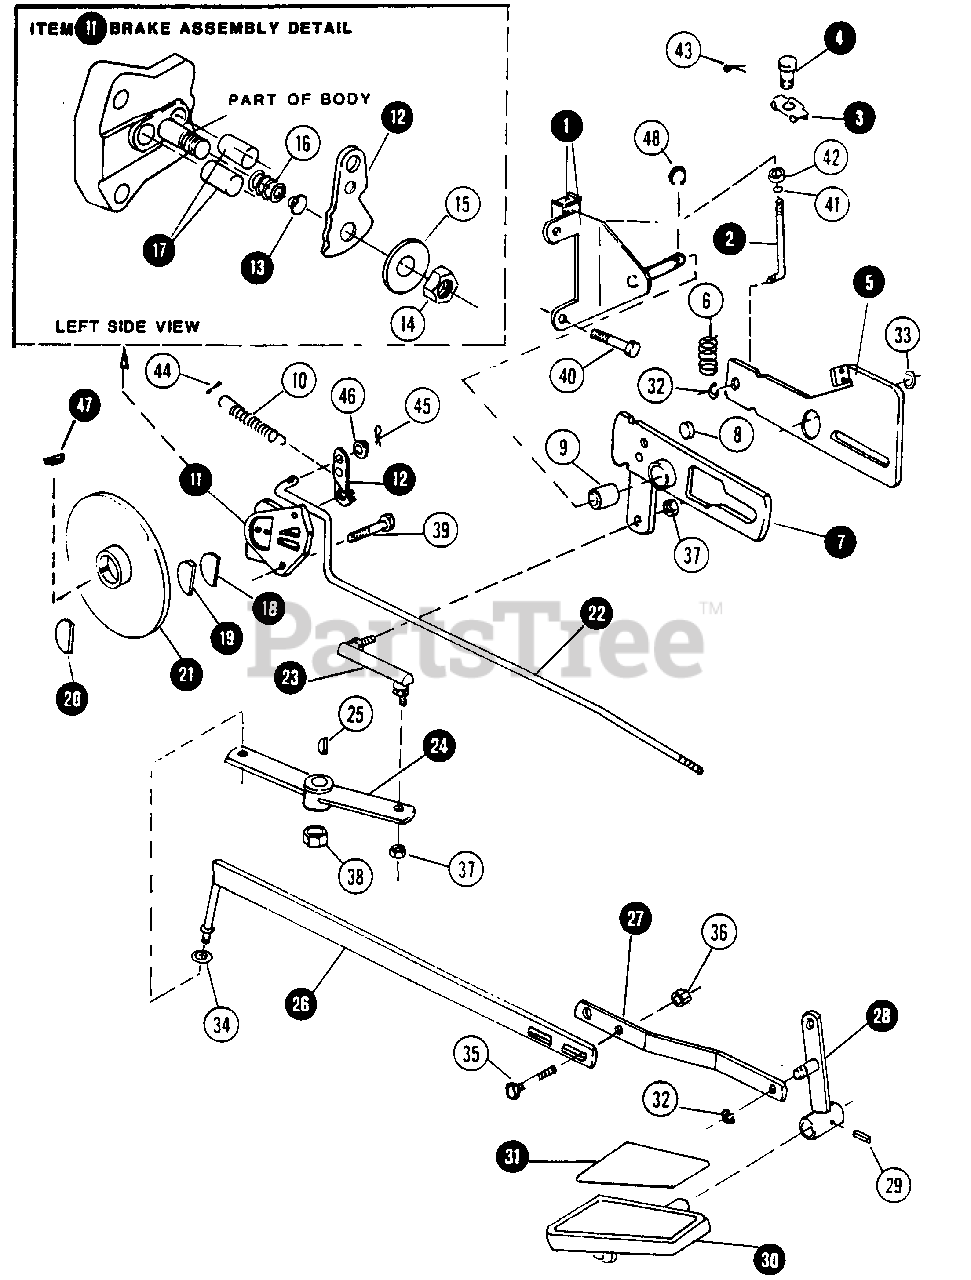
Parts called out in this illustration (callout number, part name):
1	BRACKET, TRUNNION MOUNTING
2	LINK, NEUTRAL ADJUSTING
3	RETAINER, ADJUSTING LINK
4	STUD, ADJUSTING
5	GUIDE, ROLLER
6	SPRING, NEUTRAL RETURN
7	CAM, NEUTRAL RETURN - ASSEMBLY
8	PLUG, FRICTION
9	BEARING
10	SPRING, BRAKE RETURN
11	BRAKE ASSEMBLY
13	FERRULE
14	NUT, CAM RETAINING
15	WASHER THRUST
16	SPRING, PUSH PIN
17	PIN, PUSH
18	DISC, PAD BACK-UP
19	PAD, FRICTION
20	PAD, FRICTION
21	DISC ASSEMBLY
22	ROD, AXLE BRAKE
23	LINK, TRANSMISSION LEVER
24	LEVER, DIRECTIONAL CONTROL
25	KEY, WOODRUFF
26	LINK, REAR CONTROL
27	LINK, FRONT CONTROL
28	LEVER, PEDAL PIVOT
29	PIN, GROOVE 1/4 x 1.25"
30	PEDAL, DIRECTIONAL CONTROL
31	TREAD, CONTROL PEDAL
32	RING, RETAINING
33	RING, RETAINING
34	RING, RETAINING
35	BOLT 1/4NF x 3/4 CARRIAGE
36	NUT, 1/4NF HEX
37	NUT, 3/8C HEX
38	NUT, 1/2C HEX
39	BOLT, 3/8C x 1-1/4 HEX
40	SCREW, HEX HEAD CAP 3/8-16 x 3 GR.5
41	RING, RETAINING
42	RING, ADJUSTING STUD
43	COTTER-PIN, 1/16 x 1"
44	COTTER-PIN, 5/16-1"
45	COTTER-PIN, 3/32 x 1/2"
46	WASHER, 1/4 FLAT
47	KEY, WOODRUFF
48	RING, RETAINING
